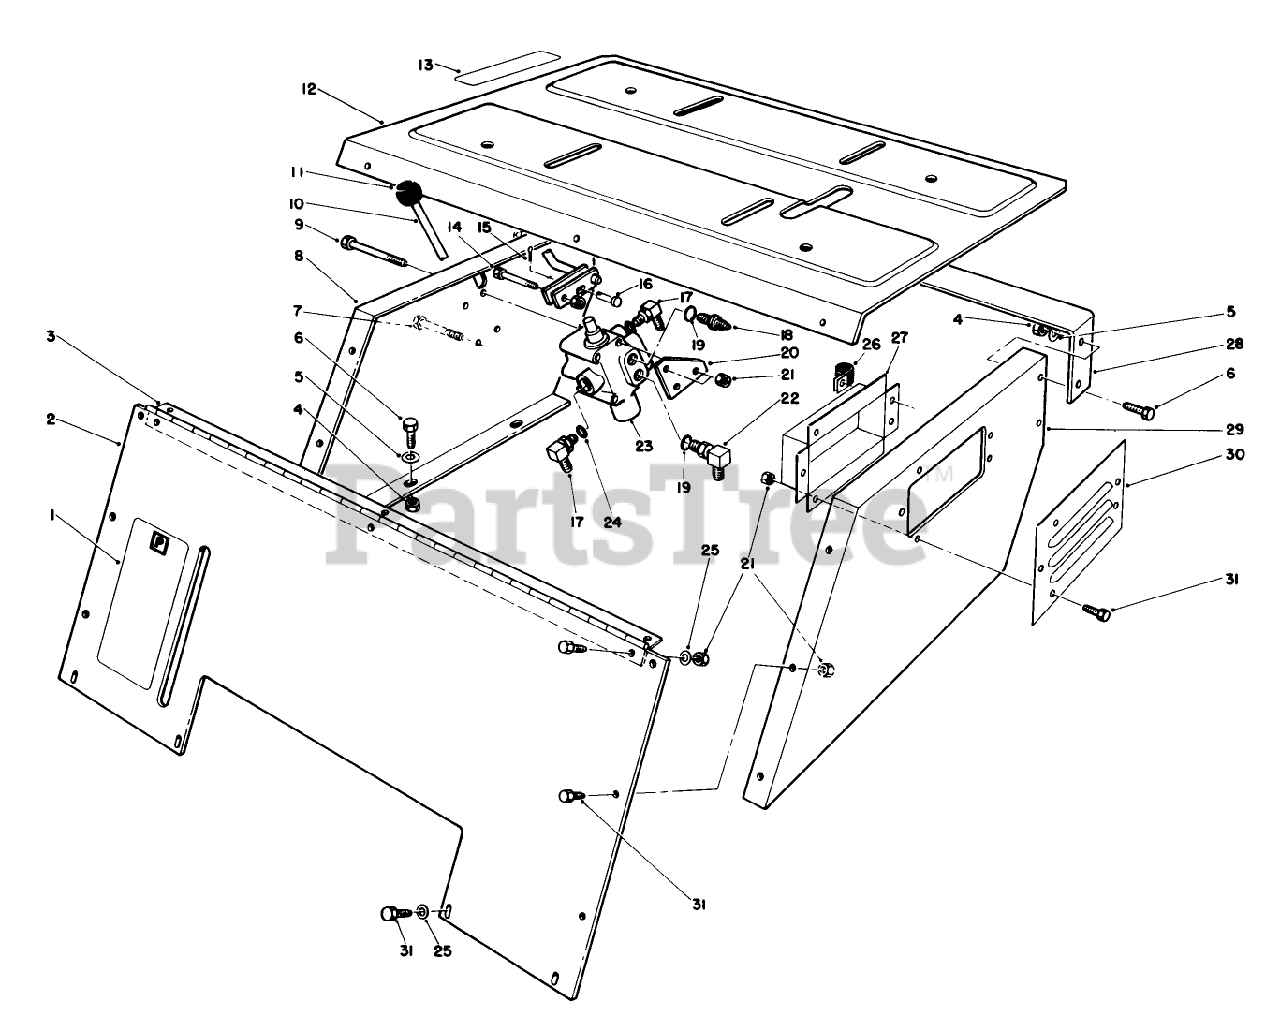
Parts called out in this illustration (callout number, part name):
1	PARK BRAKE DECAL
2	Support-Seat, Front
3	Hinge-Seat
4	NUT-LOCK, NI
5	WASHER-PLAIN
6	SCREW-HH
7	SCREW-HH
8	Support-Seat RH.
9	SCREW-HH
10	VALVE LEVER WA
12	SEAT PLATE R
13	LIFT CONTROL DECAL
14	SCREW-HH
15	PIN-COTTER
16	PIN-CLEVIS
17	FITTING-HYD, 90 DEG
18	FITTING-STRAIGHT
19	O-RING
20	VALVE LEVER BRKT
21	NUT-LOCK, NI
22	FITTING-ELBOW, 90
23	VALVE ASM
24	O-RING
25	WASHER-FLAT
26	CLAMP
27	AIR CHAMBER WA B
28	Support-Hood
29	LH SEAT SUPPORT R
30	AIR CHAMBER COVER R
31	SCREW-HH
